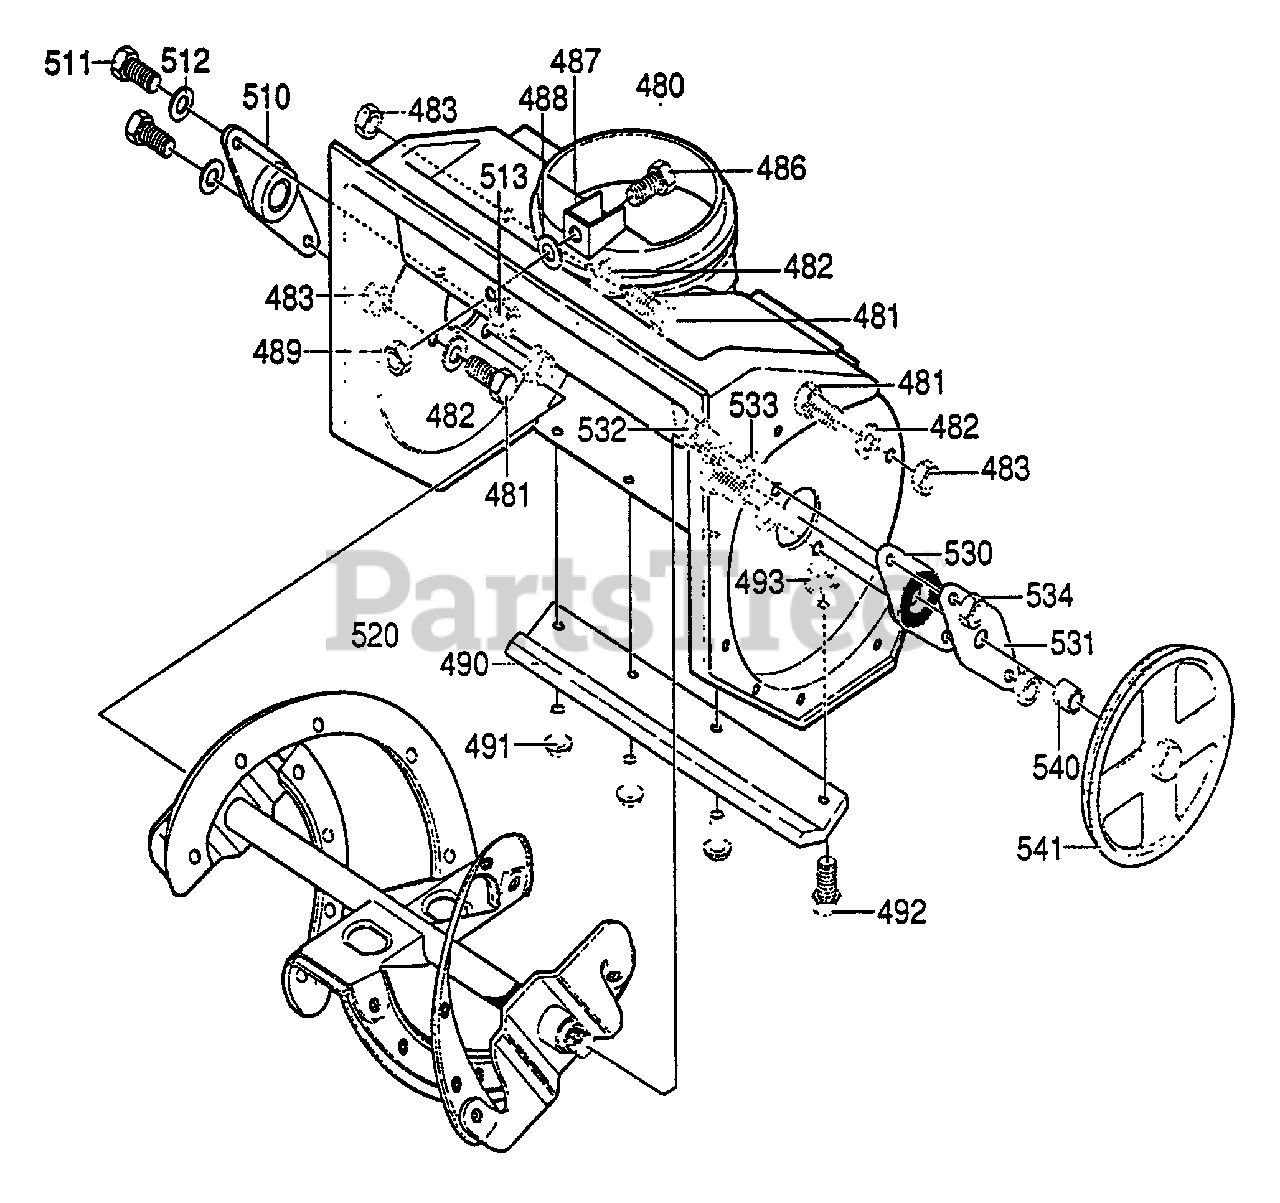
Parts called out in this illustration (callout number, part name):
480	HOUSING, RING & AUGER
481	SCREW, 1/4-20 X .75
482	WASHER, FLAT
483	NUT, 1/4-20 REG HEX CTRLK
486	SCREW, 1/4-20 X .63
487	BRACKET, STOP
488	WASHER, FLAT
489	NUT, 1/4-20 REG HEX CTRLK
490	BLADE, SCRAPER
492	SCREW, 1/4-20 X .75
493	NUT, 1/4-20
510	BRNG, FL
511	SCREW, 1/4-20 X .88
512	FLATWASHER .281 X .63 X .065
513	NUT. 1/4-20
520	AUGER, ASSY COMP
530	BRNG & PLATE, ASSY
531	RETAINER, BRNG
532	SCREW, 1/4-20 X .62
533	WASHER, FLAT
534	NUT, 1/4-20 REG HEX CTRLK
540	SPACER, SLEEVE
541	PULLEY, POLY V6
